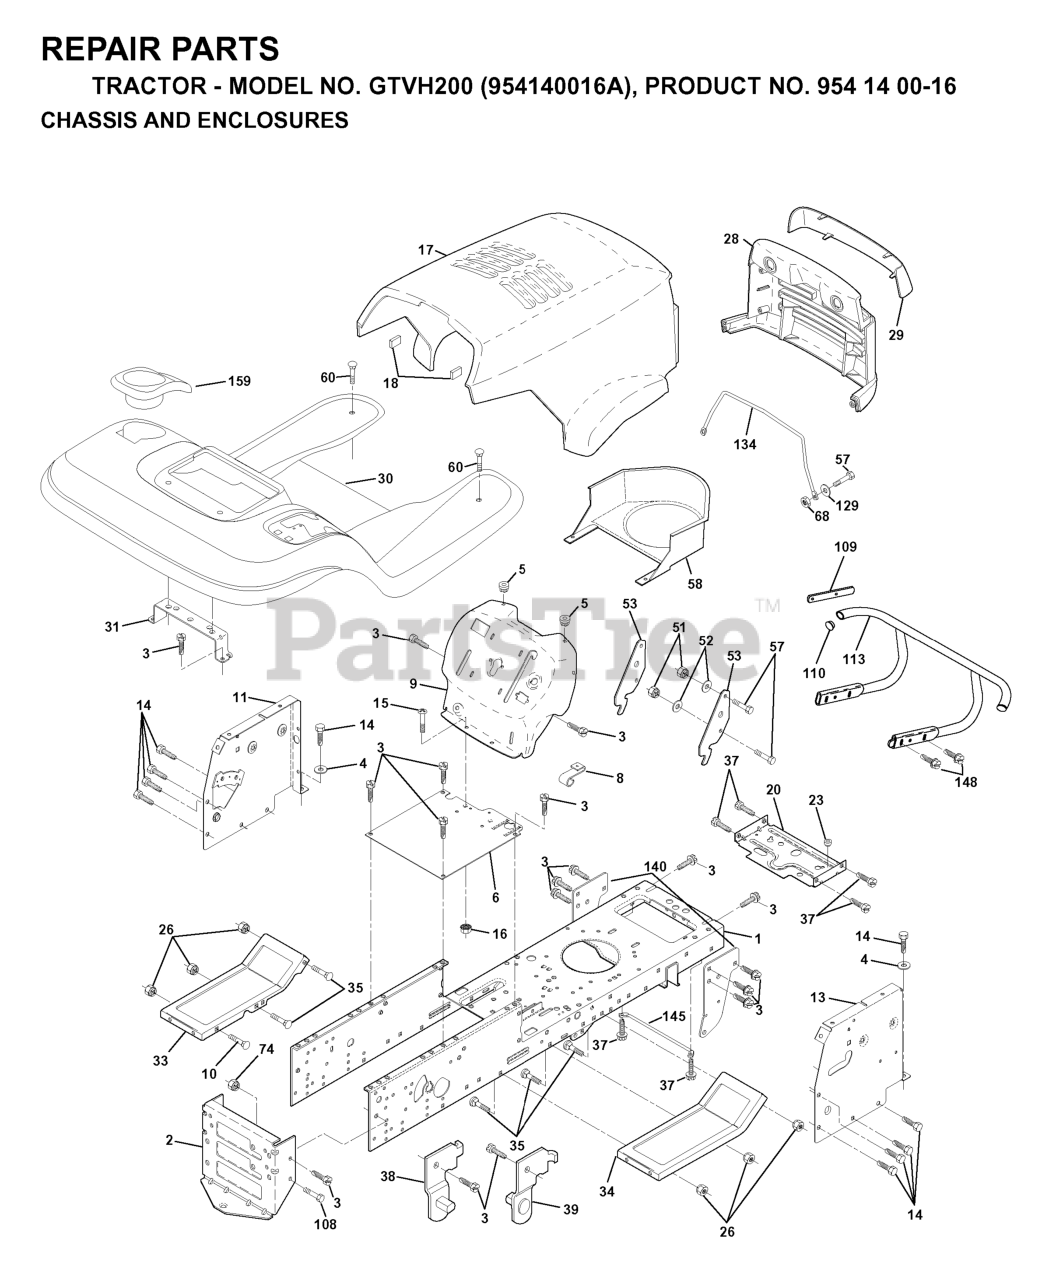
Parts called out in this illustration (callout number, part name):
1	SPROCKET
2	SPROCKET
3	SPROCKET
4	CHAIN LINK #50
5	CHAIN, #50 PERMA LUBE ROLLER
6	BEARING
7	BEARING 1"
8	V-PULLEY, A-4"X3/4" BORE W/KEY
9	V-PULLEY
10	ENGINE BELT - V
11	STAMPING KIT
12	STAMPING KIT
13	TINE ROTOR
14	OUTER ROTOR
15	CENTER TINE
16	FASTENER KIT
17	BELT KEEPER KIT
18	IDLER ARM KIT
19	IDLER PULLEY KIT
20	IDLER ARM KIT
21	IDLER SPROCKET KIT
22	FRONT WHEEL & SHAFT KIT
23	TINE SET
24	BOLT KIT
25	JACK SHAFT, W/ KEY
26	SPIKE SET NLA
27	STAMPING KIT
28	BEARING
540007103	BOLT KIT
540007112	TINE SET
